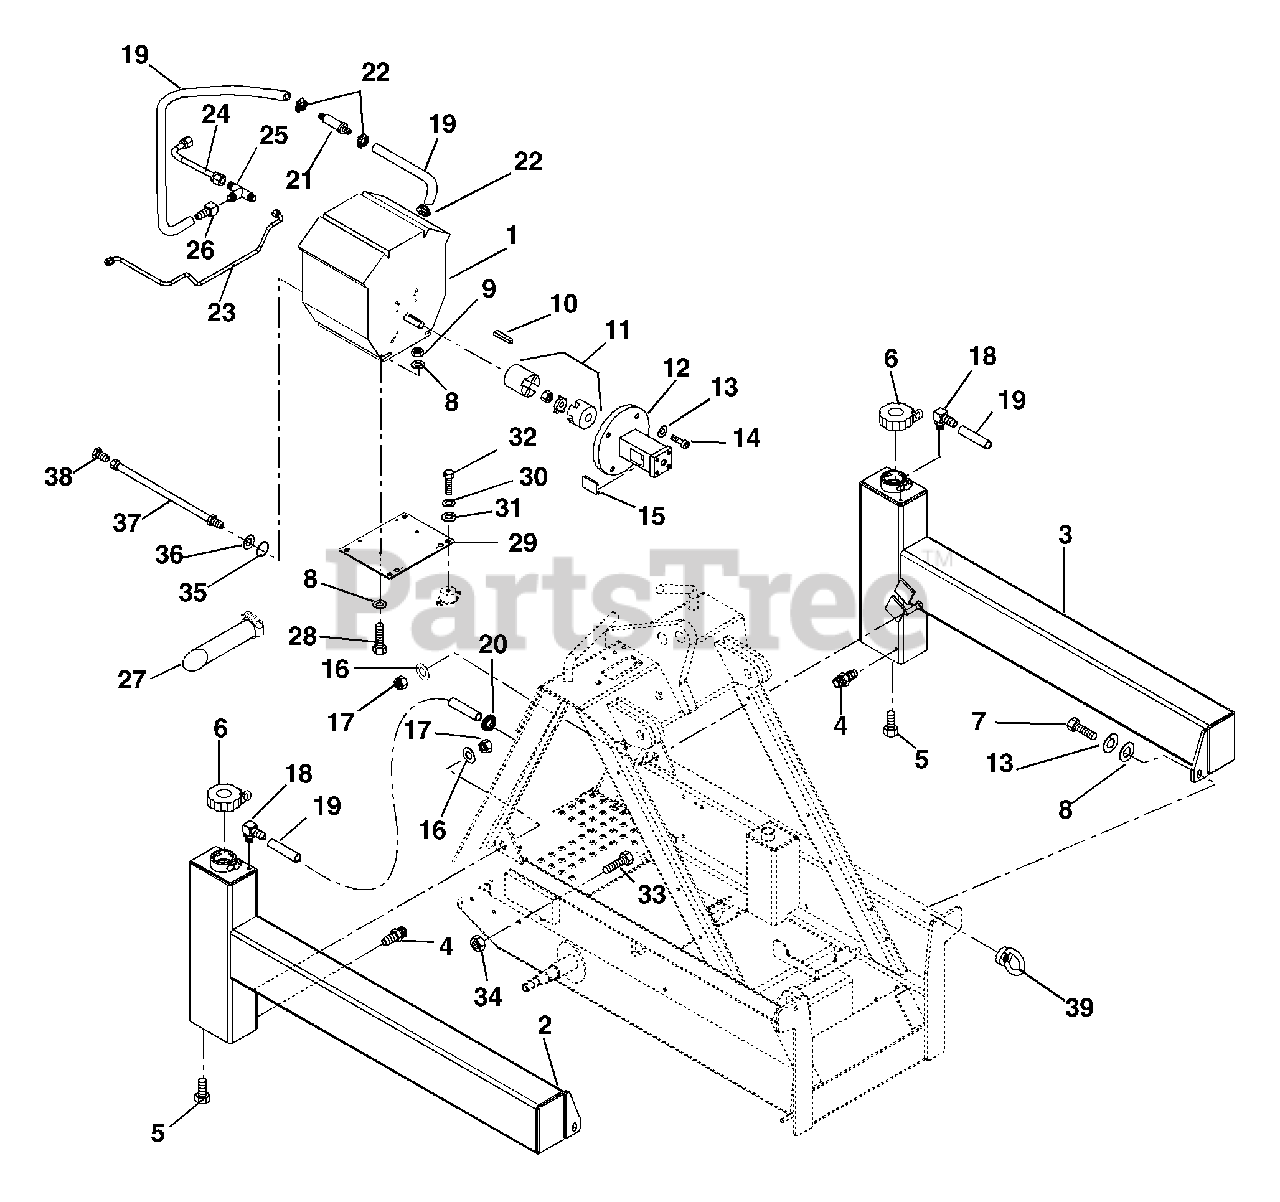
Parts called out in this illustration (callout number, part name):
1	Engine-Honda (GX620K1QDF)
1	Filter-Air Honda
1	Filter-Air Precleaner Honda
1	Plug-Spark Honda
1	Filter-Fuel Honda
1	Clip-Fuel Filter Honda
1	Filter-Engine Oil Honda Skidster
1	Wrench, Oil Filter Honda
2	Tank-Fuel Gas Right Hand
3	Tank-Fuel Gas Left Hand
4	Adapter-Male Connector .438-20 x .125-27
5	Plug-Pipe .125-27 NPT
6	Cap-Fuel Tank
7	Bolt-Hex M10-1.5 x 40
8	Washer-Flat-Steel .406 x .812 x .065
9	Nut-Locking-Nylon M10-1.5
10	Key-Square .25 x 1.25 x .25 SAE
11	Coupling
12	Bell-Housing
13	Washer-Locking .44 x .109
14	Bolt-Hex .38-16 x 1.50 Grade 5
15	Cover-Access
16	Washer-Flat-Steel .531 x 1.06 x .095
17	Nut-Locking-Nylon M12-1.75
18	Fitting-Barber 90 Degree Elbow .125-27 NPT x .25 I.D. Hose
19	Line-Gas
21	Filter-Fuel
22	Clamp-Hose
23	Tube-Fuel Line-Long
24	Tube-Fuel Line-Short
25	Adapter-Tee .56-18
26	Fitting-Hose .375-M6
27	Extension-Muffler Exhaust
28	Bolt-Hex M10-1.5 x 45
29	Mount-Engine Plate
30	Washer-Locking .50 x .125
31	Washer-Flat-Steel .531 x 1.06 x .095
32	Bolt-Hex .50-20 x 1.00 Grade 5
33	Bolt-Hex M6-1.0 x 25
34	Nut-Locking-Nylon M6-1
35	O-Ring M14 x 1.5
36	Ring, Retaining M14
37	Hose, Engine Oil Drain
38	Plug .44-20
39	Nut, Eye M10-1.5
